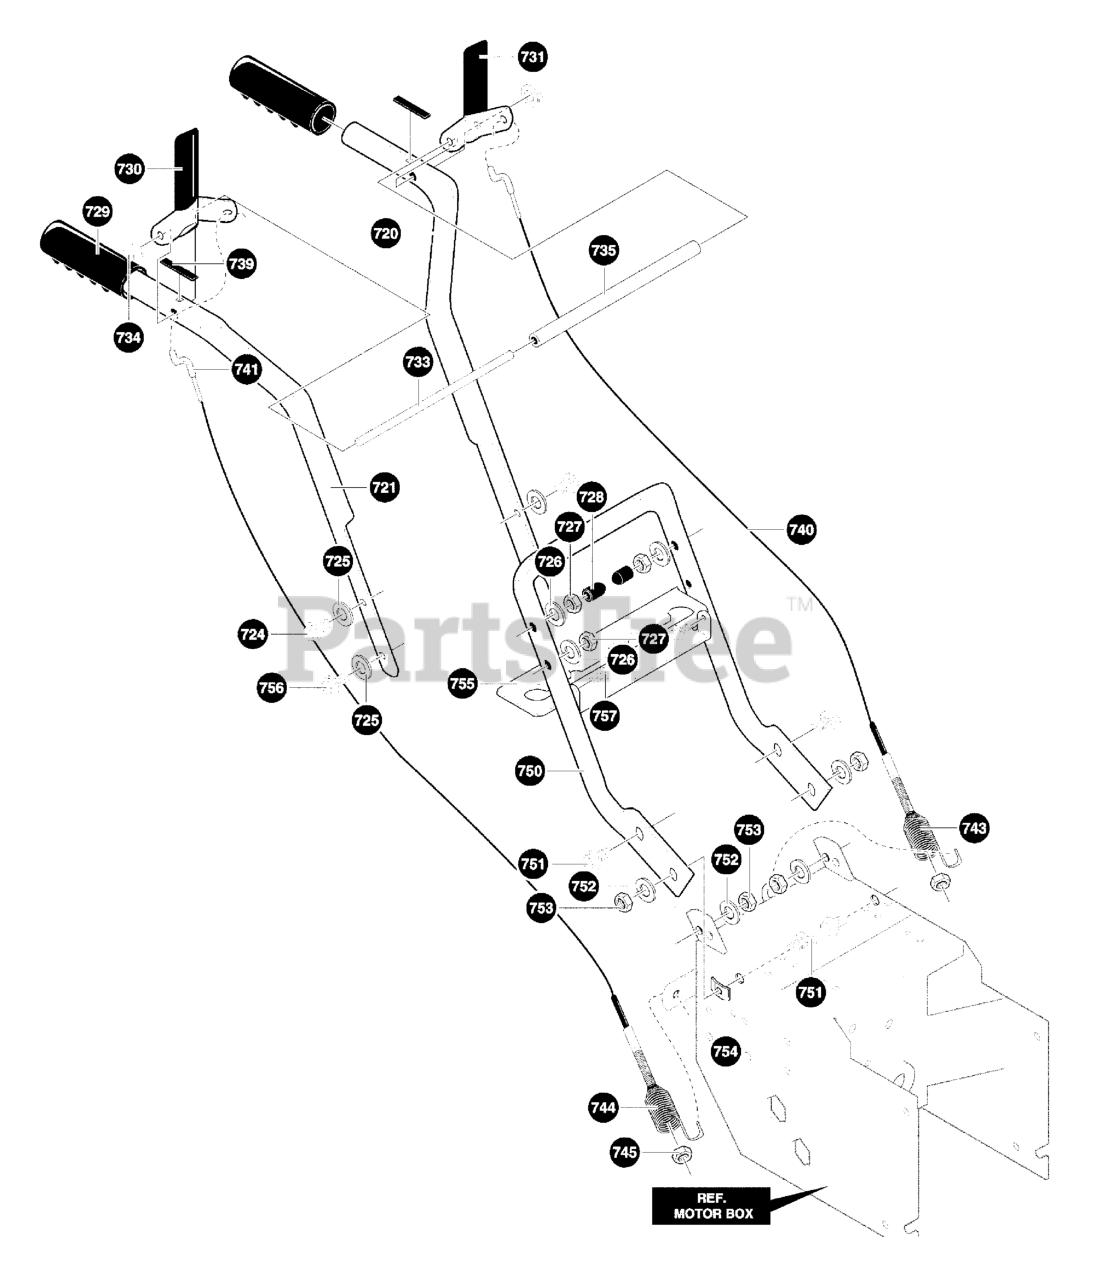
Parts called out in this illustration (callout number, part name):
720	HANDLE, UPPER LH
721	HANDLE, UPPER RH
724	SCREW, 5/16-18 x 2.75
725	WASHER, FLAT .349X.69X.066
726	WASHER, .31X.58X.08
727	NUT, 5/16-18 REGHEX
728	STOP, RED PLASTIC
729	GRIP-HANDLE FINGER
730	LEVER, ASSY CLUTCH DRIVE RH
731	LEVER, ASSY CLUTCH DRIVE LH
733	ROD, PIVOT CLUTCH
734	NUT, PUSH 1/4" HEAVY DUTY
735	SPACER - HANDLE
739	BUMPER, RECTANGLE
740	CABLE, CLUTCH 28.44LG
741	CABLE, AUGER CLUTCH 25.5"
743	SPRING, TENSION
744	SPRING, AUGER CLUTCH
745	NUT, 1/4-20 HEX NYLOCK
750	HANDLE, LOWER
751	CAPSCREW, Hex Head, 5/16-18 x 1
752	WASHER, SPTLT .31X.58X.08
753	NUT, 5/16-18 REGHEX
754	PUSHNUT, 5/16
755	BRACKET, GEAR SEL.
756	SCREW, 5/16-18 x 2.00
757	SCREW, PLASTITE
